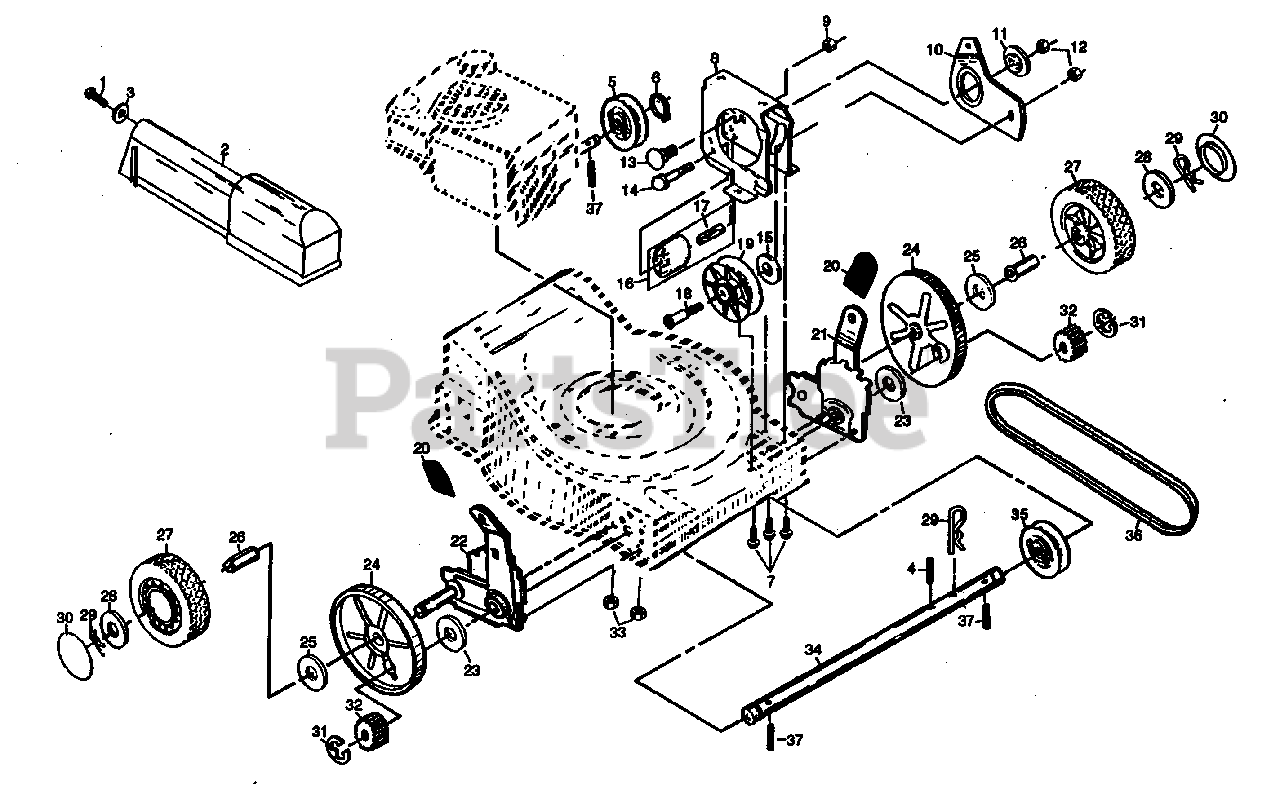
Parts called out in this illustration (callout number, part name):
1	Hex Washer Head Screw #10-24 x 1/2 (AYP part number)
2	Drive Cover (AYP part number)
3	Washer (AYP part number)
4	Drive Pawl (AYP part number)
5	Drive Pulley (AYP part number)
6	Retaining Ring (AYP part number)
7	Screw 1/4-20 x 1/2 (AYP part number)
8	Clutch Frame (AYP part number)
9	Locknut 1/4-20 (AYP part number)
10	Clutch Lever (AYP part number)
11	Clutch Lever Spacer (AYP part number)
12	Locknut 5/16-18 (AYP part number)
13	Carriage Bolt 5/16-18 x 1/2 (AYP part number)
14	Hex Head Bolt 1/4-20 x 1-1/2 (AYP part number)
15	Spacer (AYP part number)
16	Idler Assembly (AYP part number)
17	Idler Spacer (AYP part number)
18	Shoulder Bolt 5/16-18 x 1-3/8 (AYP part number)
19	Idler Pulley (AYP part number)
20	Selector Knob (AYP part number)
21	Selector Assembly (Left) (AYP part number)
22	Selector Assembly (Right) (AYP part number)
23	Felt Washer (AYP part number)
24	Dust Cover
25	Washer (AYP part number)
26	Wheel Bushing (AYP part number)
27	Wheel & Tire Assembly 8.00 x 1-3/4 (AYP part number)
28	Washer (AYP part number)
29	Retainer Clip (AYP part number)
30	Hubcap (AYP part number)
32	Pinion (AYP part number)
33	Locknut 1/4-20 (AYP part number)
34	Drive Shaft (AYP part number)
35	Driven Pulley (AYP part number)
36	Drive Belt (AYP part number)
37	Drive Pawl (AYP part number)
